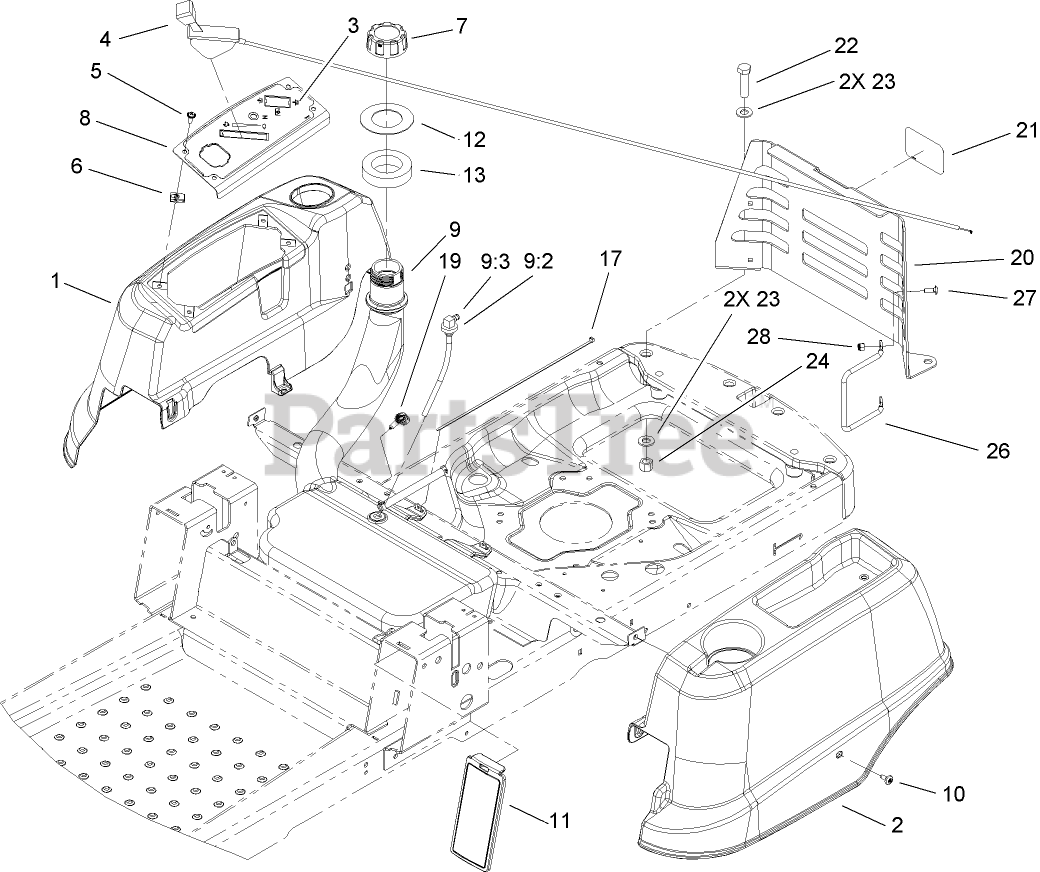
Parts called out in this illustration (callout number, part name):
3	DECAL-PANEL, CONTROL
4	CABLE-THROTTLE
5	SCREW-PRH
7	CAP-GAS
8	PANEL-CONTROL
9	FUEL TANK ASM
9:2	BUSHING
9:3	FITTING-90 DEGREE
11	COVER-CONTROL
12	WASHER-RUBBER
13	SEAL-FOAM
17	TIE-CABLE
19	CLIP-HARNESS
20	SUPPORT-COVER, REAR
21	DECAL
22	SCREW-HH
23	WASHER-FLAT
24	NUT-LOCK, NI
26	GUARD-MUFFLER
27	BOLT-CARR
28	NUT-LOCK, NI
